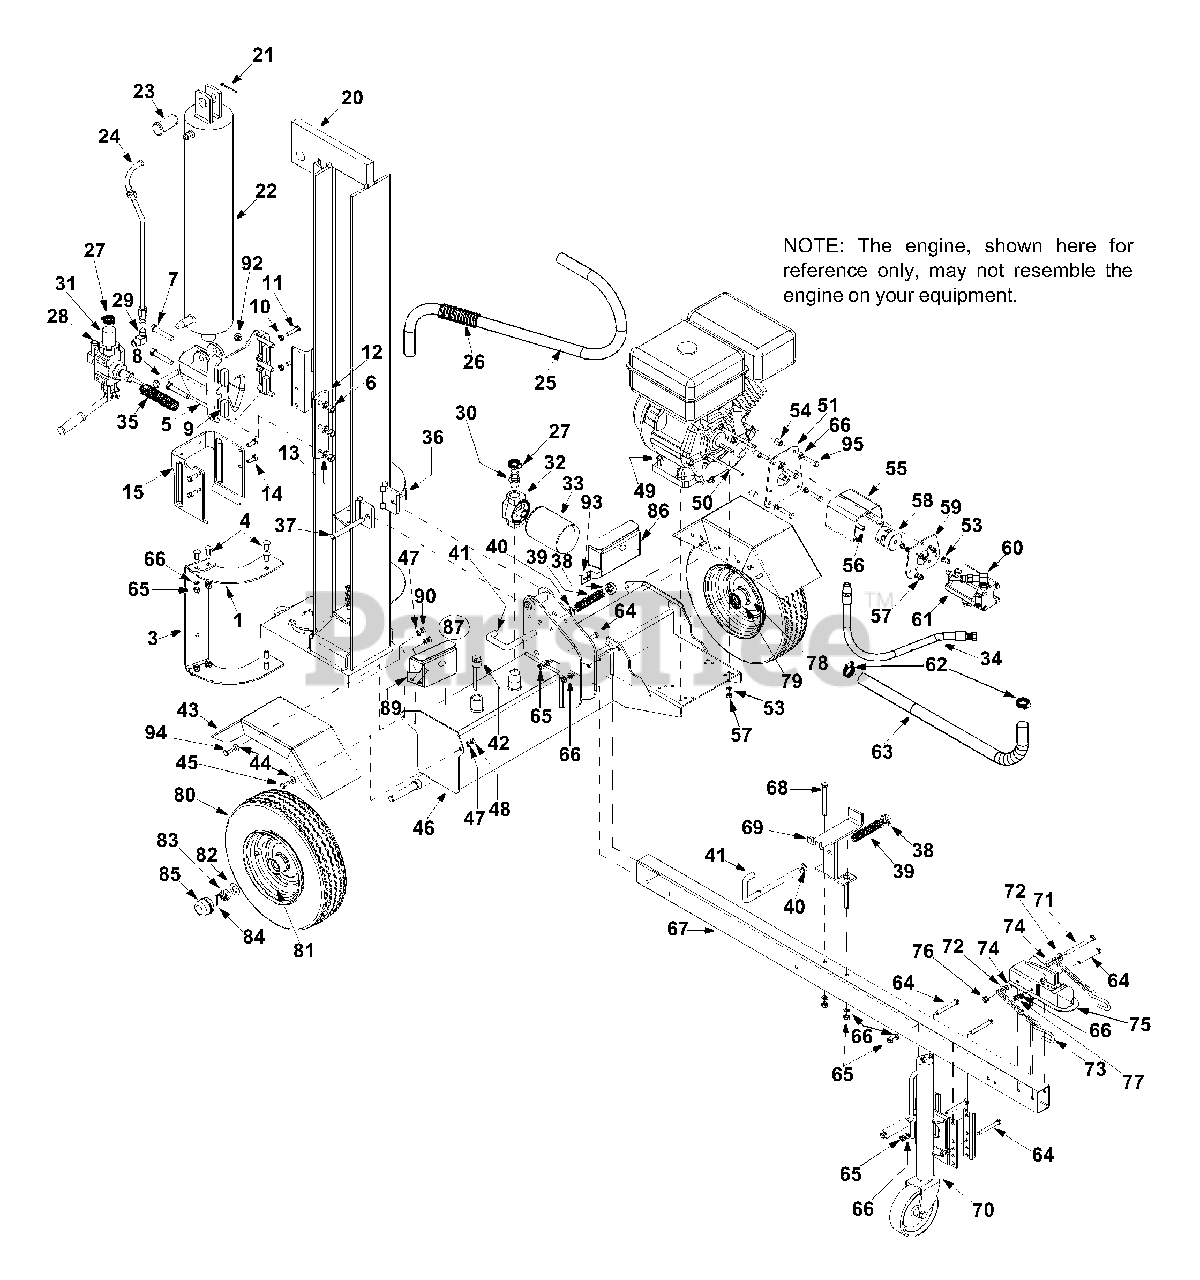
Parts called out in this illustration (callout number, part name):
4	Carriage Bolt 3/8-16 x 1.0
5	Wedge Assembly
6	Lock Nut 1/2-20
7	Hex Cap Screw 1/2-20 x 2.75
8	Hex Screw 1/2-13 x 3.25
9	Adjustable Gib
10	Hex Jam Nut 3/8-24
11	Hex Cap Screw 3/8-24 x 1.5
13	Lock Washer 1/2
14	Hex Screw 3/8-16 x 1.0
20	Beam Assembly
21	Cotter Pin
23	Clevis Pin
24	Hydraulic Tube
25	Return Hose 3/4" ID x 44" Lg.
26	Hose Guard
27	Hose Clamp 5/8"
28	Return Elbow
29	90 Degree Solid Male Adapter
30	3/4" Hose Adapter
32	Filter Housing
33	Oil Filter
34	High Pressure Hydraulic Hose
35	Hose Guard
36	Cotter Pin 1/8"
37	Hinge Pin 1/2 x 4.8" Lg.
39	Compression Spring 4"
40	Flat Washer.635 ID x.93 OD
41	Locking Rod
42	Vented Dipstick
44	Lock Washer 5/16
45	Hex Screw
46	Frame Assembly 7.0 Gal
47	Lock Washer 5/16
48	Hex Nut 5/16-18
49	Hex Cap Screw 5/16-24 x 1.75
50	Hex Cap Screw 5/16-24 x 5.25
54	Spacer.385 x.623 x.750 Lg.
55	Coupling Shield
56	Key
57	Hex Nut 5/16-24
58	Flex Coupling, 1.0 x .4375 "Stamped L090"
58	Coupling Half, 1.00
58	Coupling Half, .500
58	Spider Bushing
60	Adapter 7/8-14
61	Pump (16 gmp)
61	Pump (15 gmp) Service Kit
61	Pump (15 gmp)
62	Hose Clamp
63	Suction Hose
64	Hex Cap Screw 3/8-16 x 3.0
65	Hex Nut 3/8-16
66	Lock Washer 3/8
68	Hex Cap Screw 3/8-16 x 4.0
71	Hex Cap Screw 3/8-16 x 4.25
72	Flat Washer.385 ID x.870 OD
73	Chain
75	Hitch Coupler
76	Lock Nut 3/8-16
77	Hex Jam Nut 3/8-16
78	Bearing Seal
79	Bearing Cone
80	Wheel Assembly
82	Flat Washer.76" ID x 1.5" OD
83	Slotted Nut 3/4-16
84	Cotter Pin 5/32" x 1-1/4" Lg.
92	Lock Nut 1/2-13
93	Tinn Clip Nut 1/4-20
94	Hex Screw 5/16-24
95	Hex Screw 3/8-16 x 1.75
